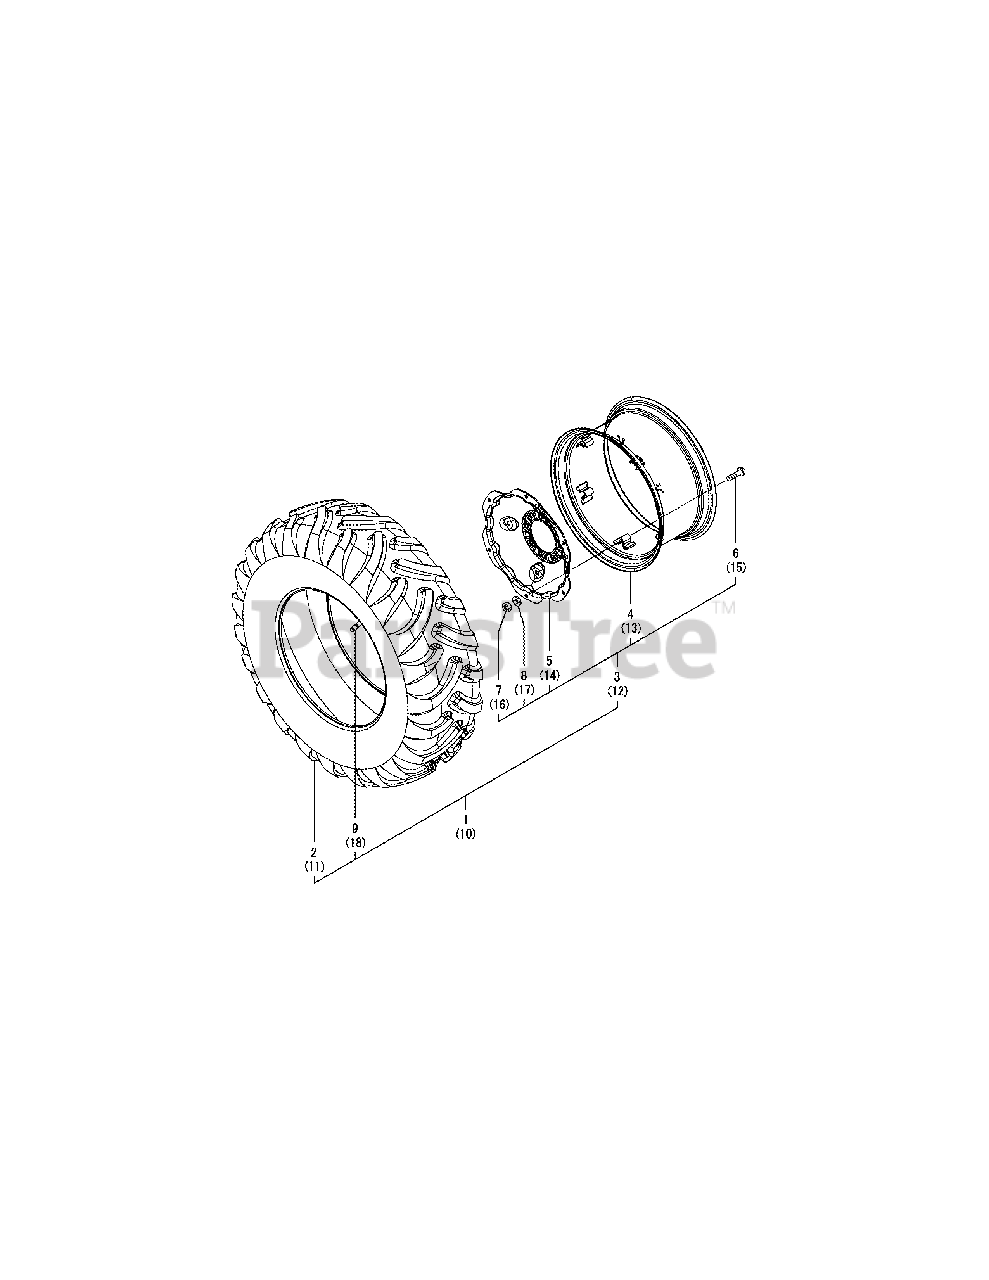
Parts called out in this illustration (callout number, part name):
1	R1 TIRE ASM,WHEEL LEFT
2	TIRE, R1 14.9X24, AG
9	VALVE, REAR TIRE
10	TIRE ASM, R1 REAR RIGHT
11	TIRE, R1 14.9X24, AG
18	VALVE, REAR TIRE
